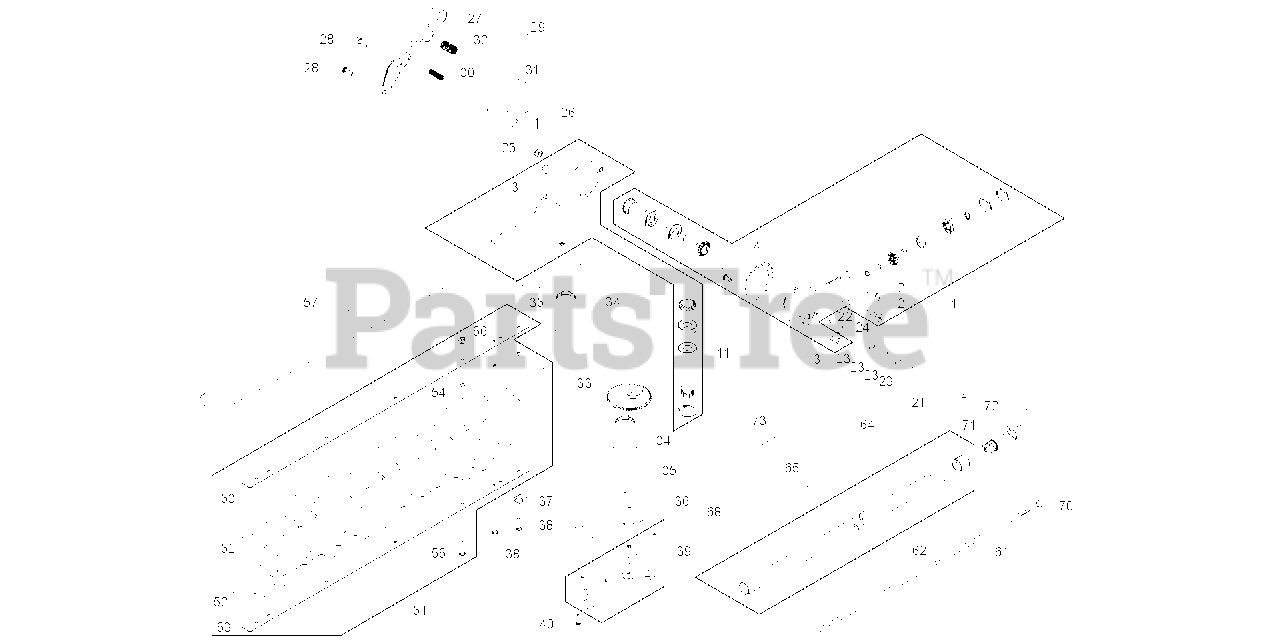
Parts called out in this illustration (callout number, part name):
1	HOUSING C, GEAR
2	BOLT, TORX (6X20)
3	BOLT, TORX (6X8)
4	O-RING (S-35)
21	BOLT, TORX (6X103)
22	O-RING (P-6)
23	SPRING, CONED DISK (DB-6H ACP)
25	NUT, CASTLE (M6)
28	BOLT, TORX (5X18)
32	SPRING, BIG
34	ROD, CONNECTING
35	PLATE, THRUST
38	BOLT, TORX (5X20)
39	COVER, GEARBOX
40	BOLT, TORX (4X16)
51	CUTTER ASSY.
55	BOLT, TORX (5X15)
56	NUT, FLANGE LOCK (M5)
57	COVER, CUTTER
61	SHAFT, DRIVE
64	MARK, ARROW
65	MARK, CAUTION
68	MARK, EMBLEM (SSHH)
